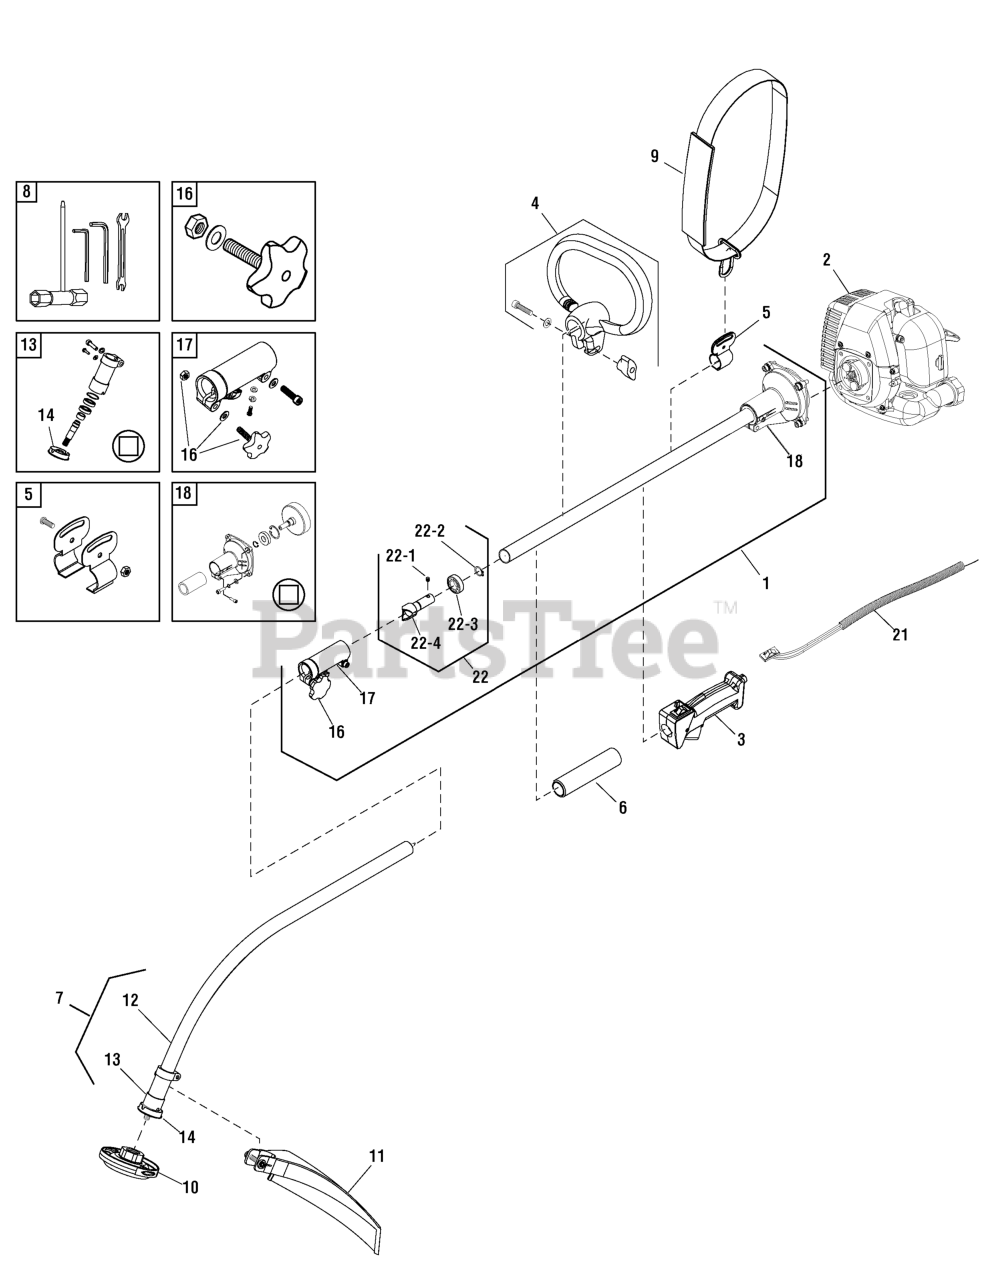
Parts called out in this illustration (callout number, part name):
1	SHAFT ASSEMBLY, Upper
2	ENGINE, 26cc 2 Stroke
3	TRIGGER HOUSING ASSEMBLY
4	HANDLE ASSEMBLY
5	BRACKET, Strap
6	POLE PAD
7	SHAFT & GEAR HEAD ASSEMBLY, Lower, Bent
8	TOOL KIT, Trimmer
9	HARNESS, Shoulder
10	TRIMMER HEAD
11	GUARD ASSEMBLY, Bent Shaft
12	SHAFT ASSEMBLY, Lower, Bent Easy Link
13	HOUSING ASSEMBLY, Square Drive, Bent Shaft
14	WASHER, Mount, Bent Shaft
16	KNOB ASSEMBLY
17	COUPLING ASSEMBLY, Easy Link (Easy Link Drive System)
18	CLUTCH & HOUSING ASSEMBLY, Square Drive
21	THROTTLE CABLE, Sleeve & Switch, Red
22	EASY LINK SOCKET & BEARING ASSEMBLY
22-4	DRIVE SOCKET
